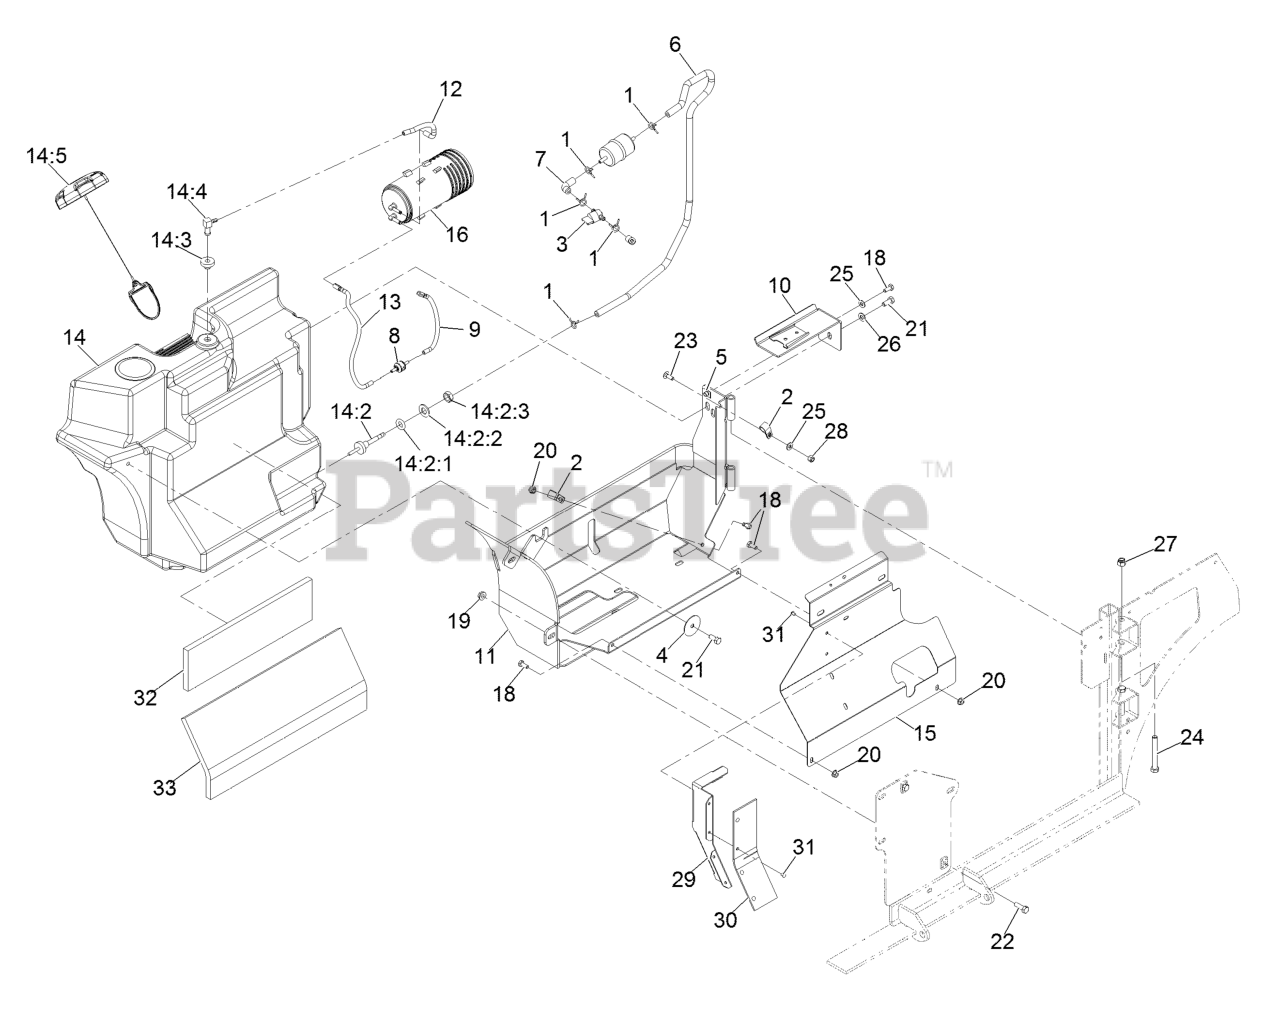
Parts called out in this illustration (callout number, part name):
2	CLIP-LOOM
3	VALVE-FUEL
5	Nut-Retainer-Panel 1/4-20
6	FUEL LINE ASM
7	HOSE-FUEL
9	HOSE-VENT, FORMED
10	CANISTER BRACKET ASM
11	TANK FRAME ASM
12	HOSE-VENT, FORMED
13	HOSE-VENT, FORMED
14	FUEL TANK ASM
14:2	FITTING-FUEL, BULKHEAD
14:2:1	O-RING,BULKHEAD FITTING
14:2:2	WASHER-FLAT
14:2:3	NUT-JAM
14:3	BUSHING
15	PANEL-TANK SHIELD
16	CANISTER-CARBON, 800CC
18	SCREW-HH
21	SCREW-HH
22	SCREW-HH
23	BOLT-CARR
24	SCREW-CARR
25	WASHER-FLAT
26	WASHER-PLAIN
27	NUT-LOCK, NI
28	NUT-LOCK, NI
29	DEFLECTOR-AIR
30	FLAP-RUBBER
31	RIVET-POP
32	INSULATION-FOAM PAD, FRON
33	INSULATION-FOAM PAD, REAR
